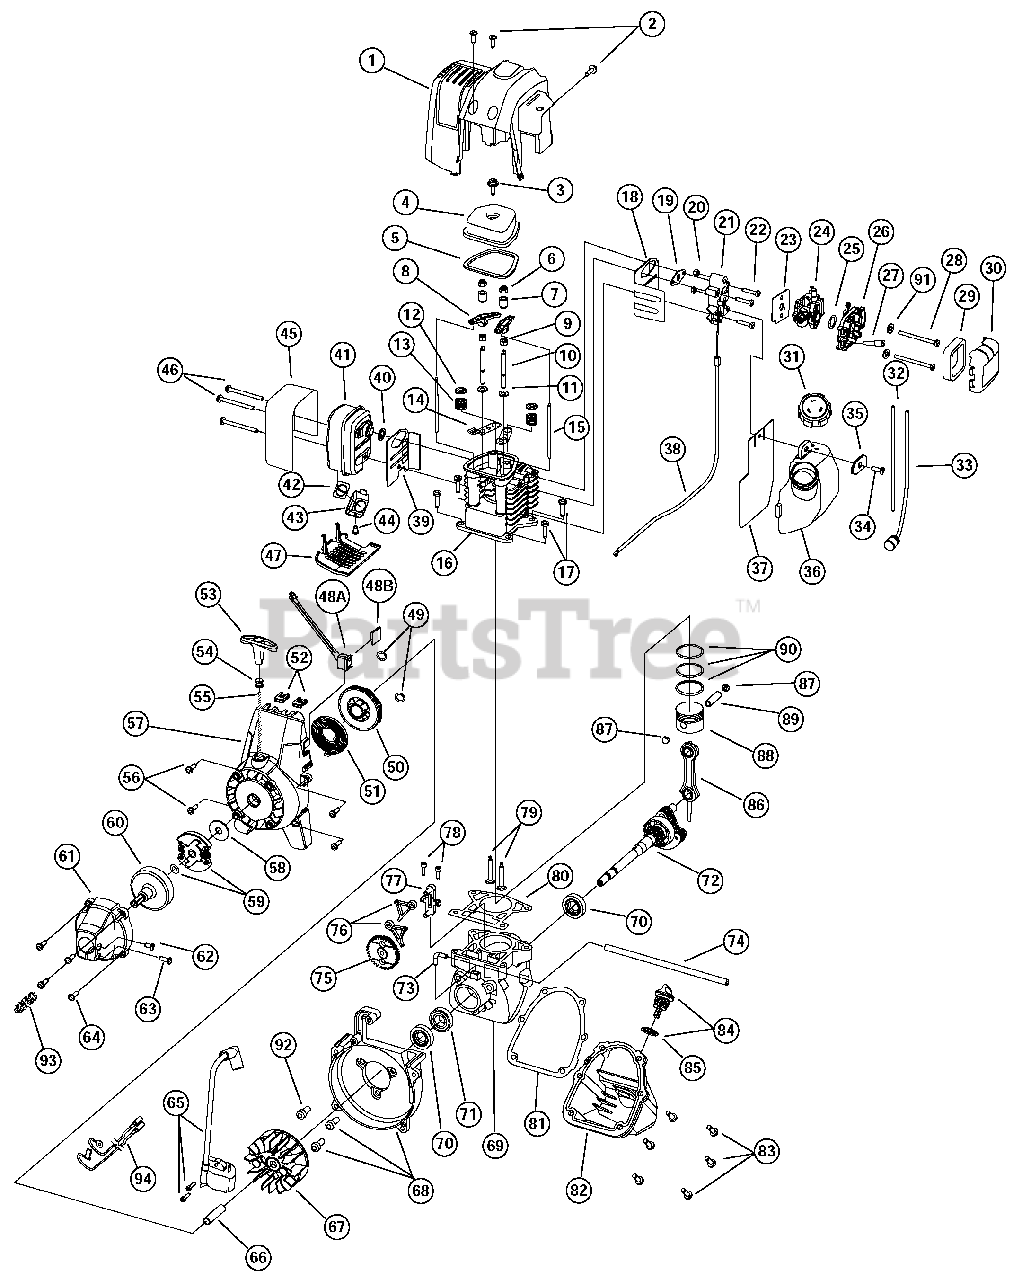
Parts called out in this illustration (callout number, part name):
1	Engine Cover
2	Engine Cover Screws
3	Valve Cover Screw
4	Valve Cover
5	Valve Cover Gasket
6	Rocker Adjustment Nut
7	Rocker Arm Pivot
8	Rocker Arm
9	Hex Nut
10	Rocker Arm Stud
12	Valve Spring Retainer
13	Valve Spring
14	Push Rod Guide
15	Push Rod
16	Cylinder Head
17	Cylinder Screw
18	Intake Baffle
19	Carburetor Mount Gasket
20	Nut
21	Carburetor Mount
22	Carburetor Mount Screw
23	Carburetor Gasket
24	Carburetor with Primer
25	O-Ring, Carburetor
26	Air Filter Assembly
28	Air Filter Mounting Screw
29	Air Filter
30	Air Filter Cover
31	Fuel Cap
32	Fuel Return Line
33	Fuel Pick-Up Line with Filter
36	Fuel Tank Assembly
37	Fuel Tank Shield
38	Throttle Cable
39	Muffler Baffle
40	Muffler Gasket
41	Muffler
42	Spark Arrestor Screen
43	Screen Cover
45	Muffler Shield
46	Muffler Mounting Screw
47	Muffler Cover
48A	Switch with Wires (Used with Version A Grip)
48B	Grommet (Used with Version B Grip)
49	Pulley Retainer Assembly
50	Recoil Pulley
51	Recoil Spring
52	Nut Clip
53	Pull Handle
54	Rope Guide
56	Starter Housing Screw
57	Starter Housing Assembly
58	Clutch Washer
59	Clutch with Spacer
60	Clutch Drum
61	Clutch Cover
62	Anti-Rotation Screw
64	Clutch Cover Screw
65	Ignition Module with Screws
67	Flywheel
68	Shroud Assembly with Screws
69	Crankcase Assembly
70	Oil Seal
71	Bearing
72	Crankshaft
73	90° Elbow
74	Breather Hose
75	Cam Gear
76	Cam Follower
77	Cam Bracket
78	Cam Bracket Screw
79	Valves, Intake and Exhaust
80	Cylinder Gasket
81	Oil Pan Gasket
82	Oil Pan
83	Oil Pan Screw
84	Dipstick Assembly
86	Connecting Rod
87	Wrist Pin Button
88	Piston
89	Wrist Pin
90	Piston Ring Set
93	Compression Spring
94	Coil Wire Assembly
